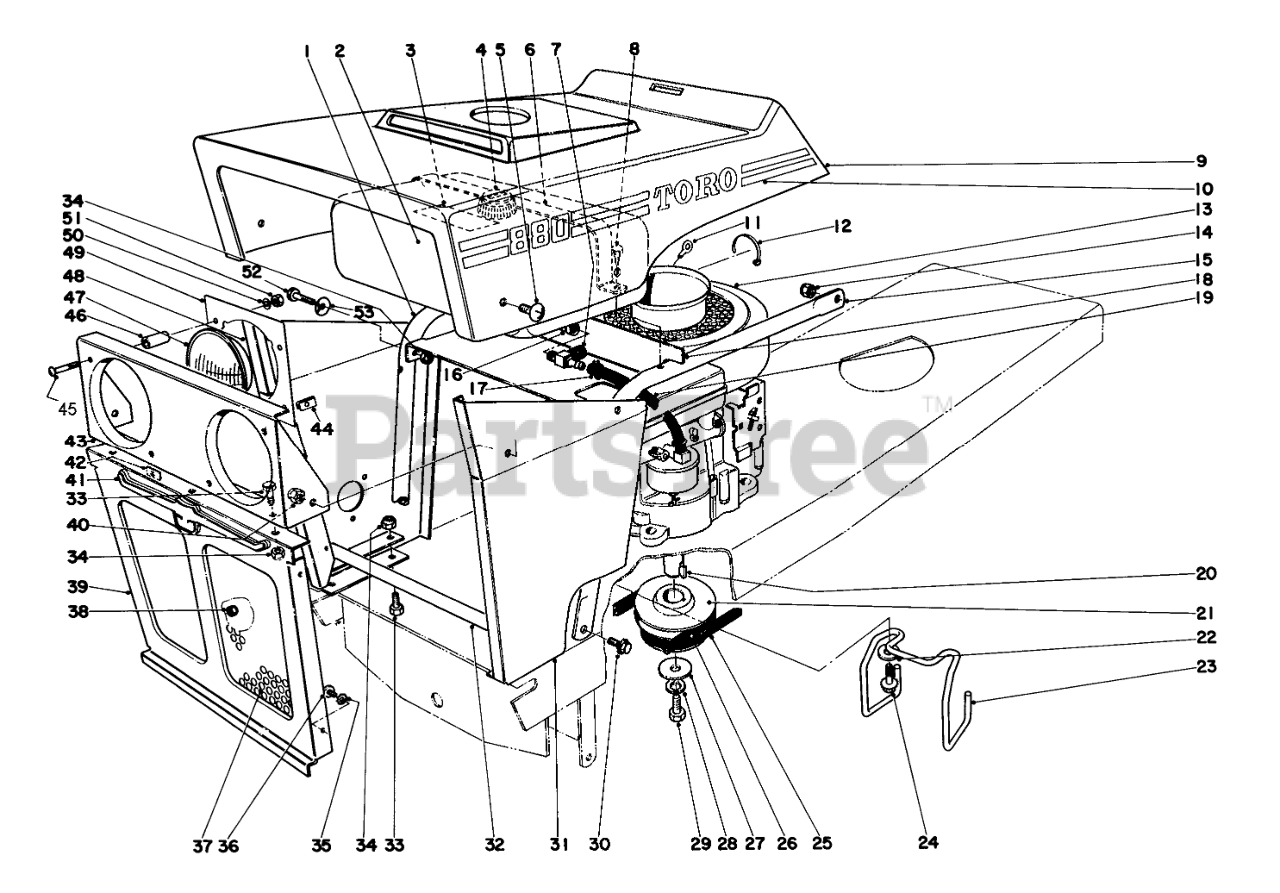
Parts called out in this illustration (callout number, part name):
1	Support-R.H.
2	Gas Tank
3	Decal
4	Gas Cap
5	Round Head Screw
6	Hold Down Gas Tank
7	Shut Off Valve
8	SCREW-HWHTF
10	Decal Hood L.H.
12	Cable Tie
13	Engine
14	NUT-LOCK, CONE
15	Support Left
16	Elbow
17	Clamp
18	Tray Gas Tank
20	KEY-WOODRUFF
21	Engine Pulley
22	WASHER-FLAT
23	Belt Guide
24	1/4-20X5/8 THDG SEMS
25	V BELT TRACTION
26	V BELT PTO
27	WASHER-FLAT
28	WASHER-LOCK
29	SCREW-HH
30	SCREW-HH
31	Skin Left Front
32	Hinge
33	SCREW-HH
34	NUT-LOCK, CONE
35	WASHER-LOCK, EXT
36	10-24 X 3/8 PAN HD SC
37	Grille Panel
38	NUT-LOCK, NI
39	Grille
40	NUT-LOCK, CONE
41	Bullshead
42	Timmerman Nut
43	Headlamp Panel
44	NUT-CLIP,U
46	Spacer
47	HEAD LAMP
48	Skin Right Front
49	Headlight Holder
50	WASHER-LOCK/SP
51	NUT-HEX
52	SCREW-HH
53	WASHER
